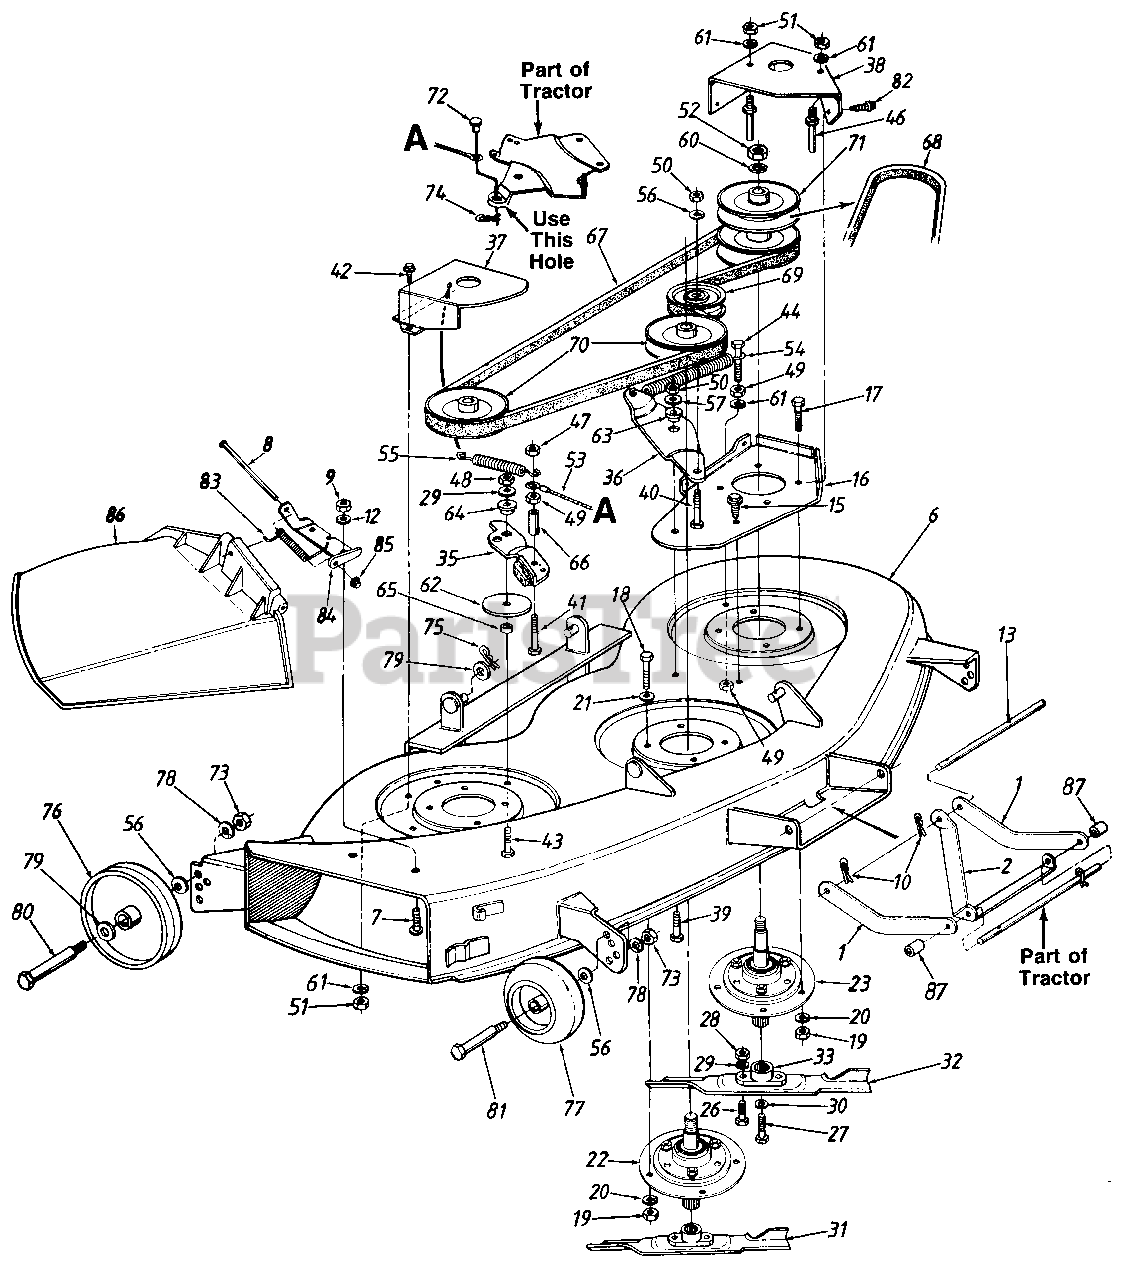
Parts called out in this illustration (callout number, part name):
7	Hex Bolt 1/4-20 x .62" Lg.
8	Hinge Pin
9	Hex Jam Nut 1/4-20 Thd.
12	Bell-Wash. l/4" I.D.
13	Deck Connecting Rod
15	Hex TT-Tap Scr. 5/16-18 x .62"
18	Hex Bolt 5/16-24 x .75" Lg.
19	Hex Nut 5/16-24 Thd.
20	L-Wash. 5/16" I.D.
21	Bell-Wash. 5/16" I.D.
22	Spindle Ass'y.
23	Spindle Ass'y.
26	Hex Bolt 5/16-24 x 1.0" Lg.
27	Hex Cl-Bolt 3/8-24 x .88" Lg.
28	Hex Nut 5/16-24 Thd.
29	L-Wash. 5/16" I.D.
30	L-Wash. 3/8" I.D.-H.D.
31	High Lift Blade 14.88" Lg.
32	High Lift Blade 16.28" Lg.
33	Blade Adapter
35	Deck Brake Brkt. Ass y.
36	Idler Bracket
40	Hex Bolt 3/8-24 x 1.5" Lg.
41	Hex Bolt 1/4-28 x 1.75" Lg.
42	Hex Wash. Hd. Tap-Scr. 1/4-20 x .5" Lg.
43	Hex Bolt 5/16-24 x 1.25" Lg. (Grade 5)
44	Hex Bolt 1/4-28 x 1.5" Lg.
46	Belt Guard Pin 1/4" Dia.
47	Hex Cent. L-Nut 1/4-28 Thd.
48	Hex Nut 5/16-24 Thd
49	Hex Nut 1/4-28 Thd.
50	Hex Nut 3/8-24 Thd.
51	Hex Nut 1/4-20 Thd. *
52	Hex Jam Nut 5/8-18 Thd.
53	Brake Cable Ass y.
54	Extension Spring 6.17" Lg.
55	Extension Spring 3.97n Lg.
56	Bell-Wash. .38" I.D. x .88n O.D.
57	Bell-Wash. .39" I.D. x 1.13" O.D.
60	Bell-Wash. 618n l.D. x 1.25" O.D.
61	L-Wash. 1/4n l.D.
62	Fl-Wash. 5/16" I.D. x 3" O.D.
63	Shld. Spacer .625" I.D.
64	Shld. Spacer
65	Spacer.34" I.D.
66	Spacer.326" I.D.
67	V-Belt
68	V-Belt
69	Fl-ldler w/Flanges 3.5" O.D.
70	Pulley 5.0n Dia.
71	Pulley 5.0n Dia.
72	Clevis Pin 1/4" Dia. x .53" Lg.
73	Hex Nut 3/8-16 Thd.
74	Intern. Cotter Pin 5/16" Dia.
75	Intern. Cotter Pin 3/8 Dia.
76	Deck Wheel 5" Dia.
77	Deck Wheel w/lnsert 5n Dia.
78	L-Wash. 3/8" I.D.
79	Fl-Wash. .531" I.D.
80	Shoulder Bolt .498n Dia. x 1.64" Lg.
81	Shoulder Bolt
82	Hex Wash. Hd. Tap-Scr. 1/4-20 x .38" Lg.
83	Torsion Spring
84	Hinge Mtg. Brkt.
86	Chute Ass'y. Comp.
87	Spacer 5/8" I.D. x 7/8" O.D.
